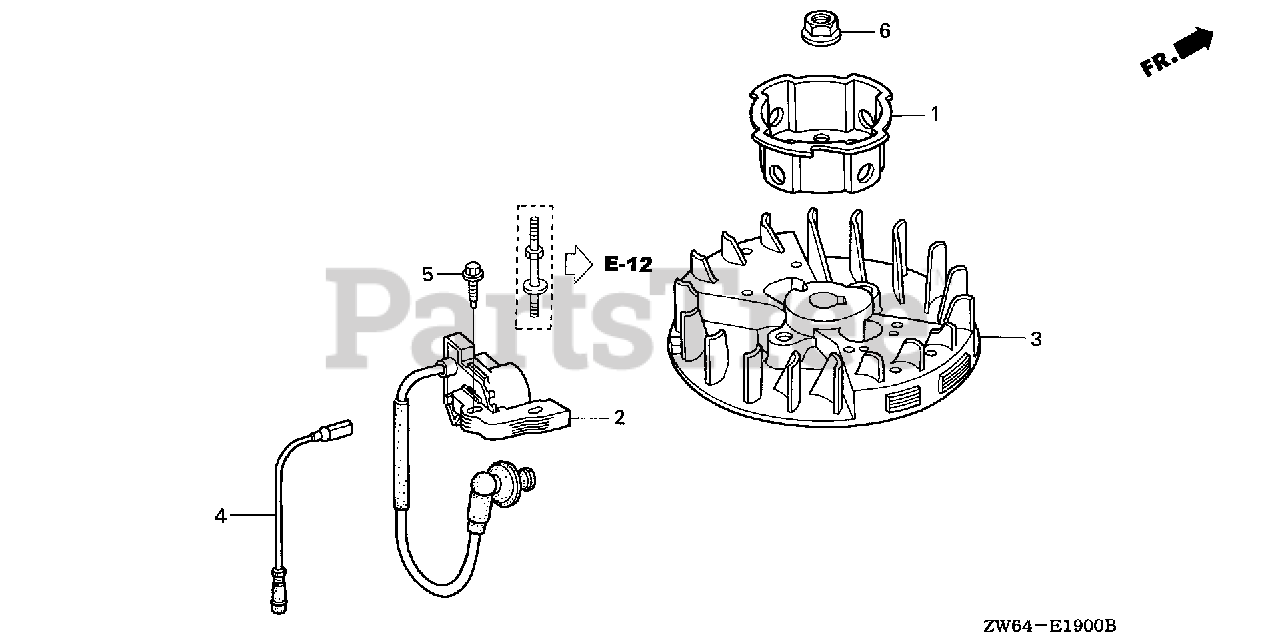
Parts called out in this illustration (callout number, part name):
1	PULLEY, STARTER
2	COIL ASSY., IGNITION
4	WIRE, STOP SWITCH
5	BOLT, FLANGE (5X20)
6	NUT, FLANGE (10MM)
